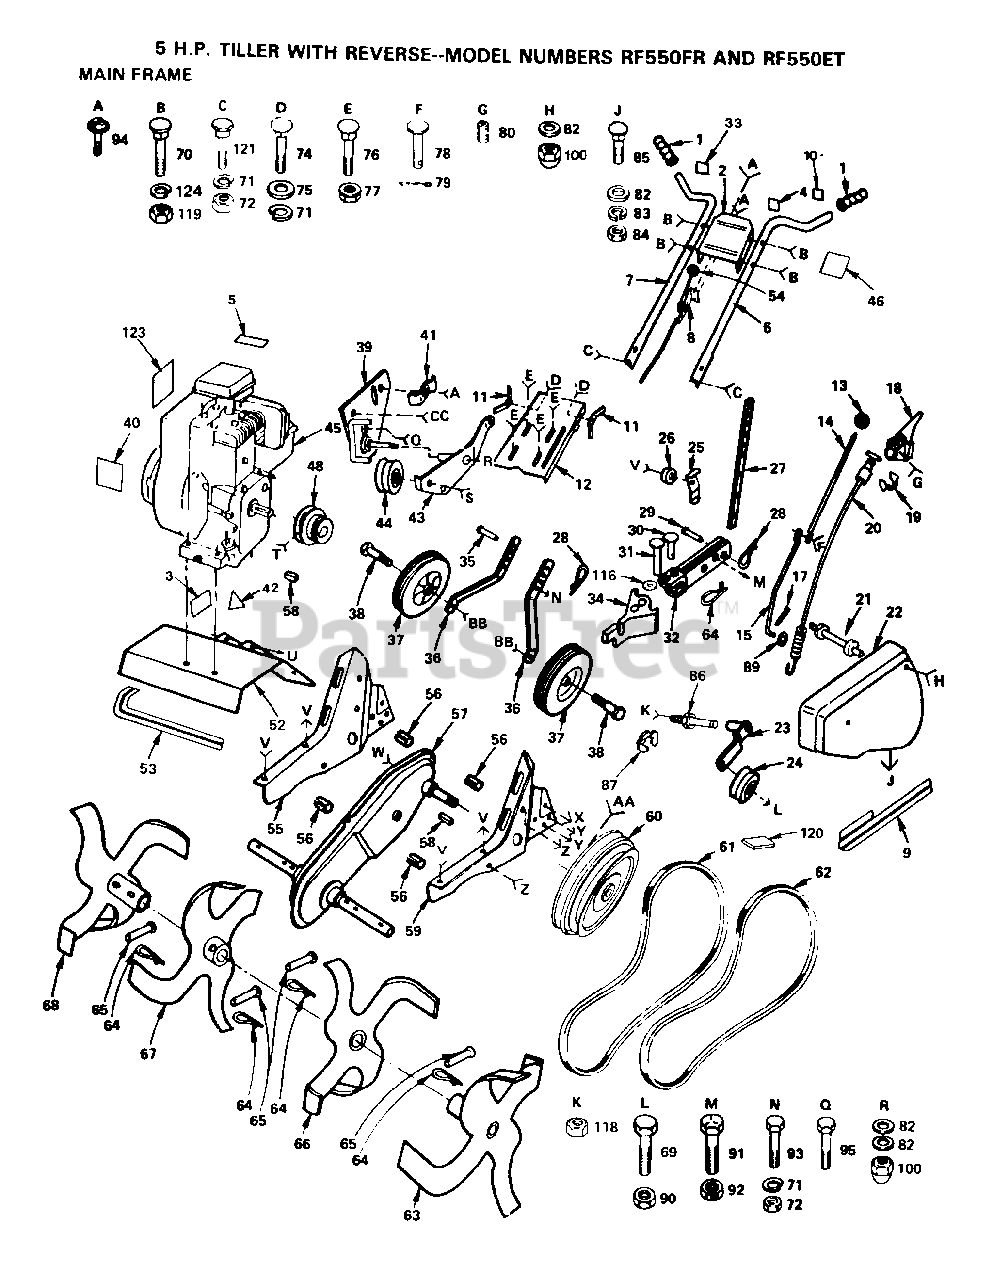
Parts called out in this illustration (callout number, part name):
2	HANDLE BRACKET
3	DECAL TI
4	DECAL, THROTTLE
5	DECAL TI
9	DECAL - BELT GUARD
10	DECAL TI
14	ROD REVERSE TI
15	REVERSE ROD TI
17	COTTER PIN
18	CONTROL LEVER TI
19	E-RING
20	CABLE CLUTCH T
21	BOLT TI
23	IDLER ARM TI
25	STAKE SPRING TI
28	SPRING.RETAINER
31	RIVET
32	STAKE HOLDER TI
33	DECAL - HAND PLACEMENT
33	DECAL TI
34	STAKE PIVOT TI
35	DRILLED RIVET RT
37	WHEEL TI
38	BOLT M
39	BRACKET ASSY TI
41	CONDIUT CLIP T
42	DECAL - OPEI
43	REV IDLER ARM TI
44	PULLEY W/SPACER
46	DECAL - HANDLE BRACKET
48	ENGINE PULLEY TI
53	DECAL - TINE SHIELD
56	SPLIT SPACER RT
58	KEY T
59	BRACKET.ENG.LH.
63	TINE WELDMENT TI
64	RETAINER.SPRING
65	RIVET.PAN HD.1.75
66	TINE TI
67	TINE TI
68	TINE WELDMENT TI
71	LOCKWASHER
72	NUT.HEX.5/16-18
74	BOLT
75	WASHER
77	NUT
78	RIVET.RD.HD.DRILL
80	SCREW
82	WASHER
83	LOCKWASHER
86	SHAFT IDLER TI
87	KLIP RING TI
89	WASHER
90	NUT
92	GRIPCO NUT
100	NUT-CAP TI
118	JAM NUT TI
120	PAD IDLER TI
123	WASHER
